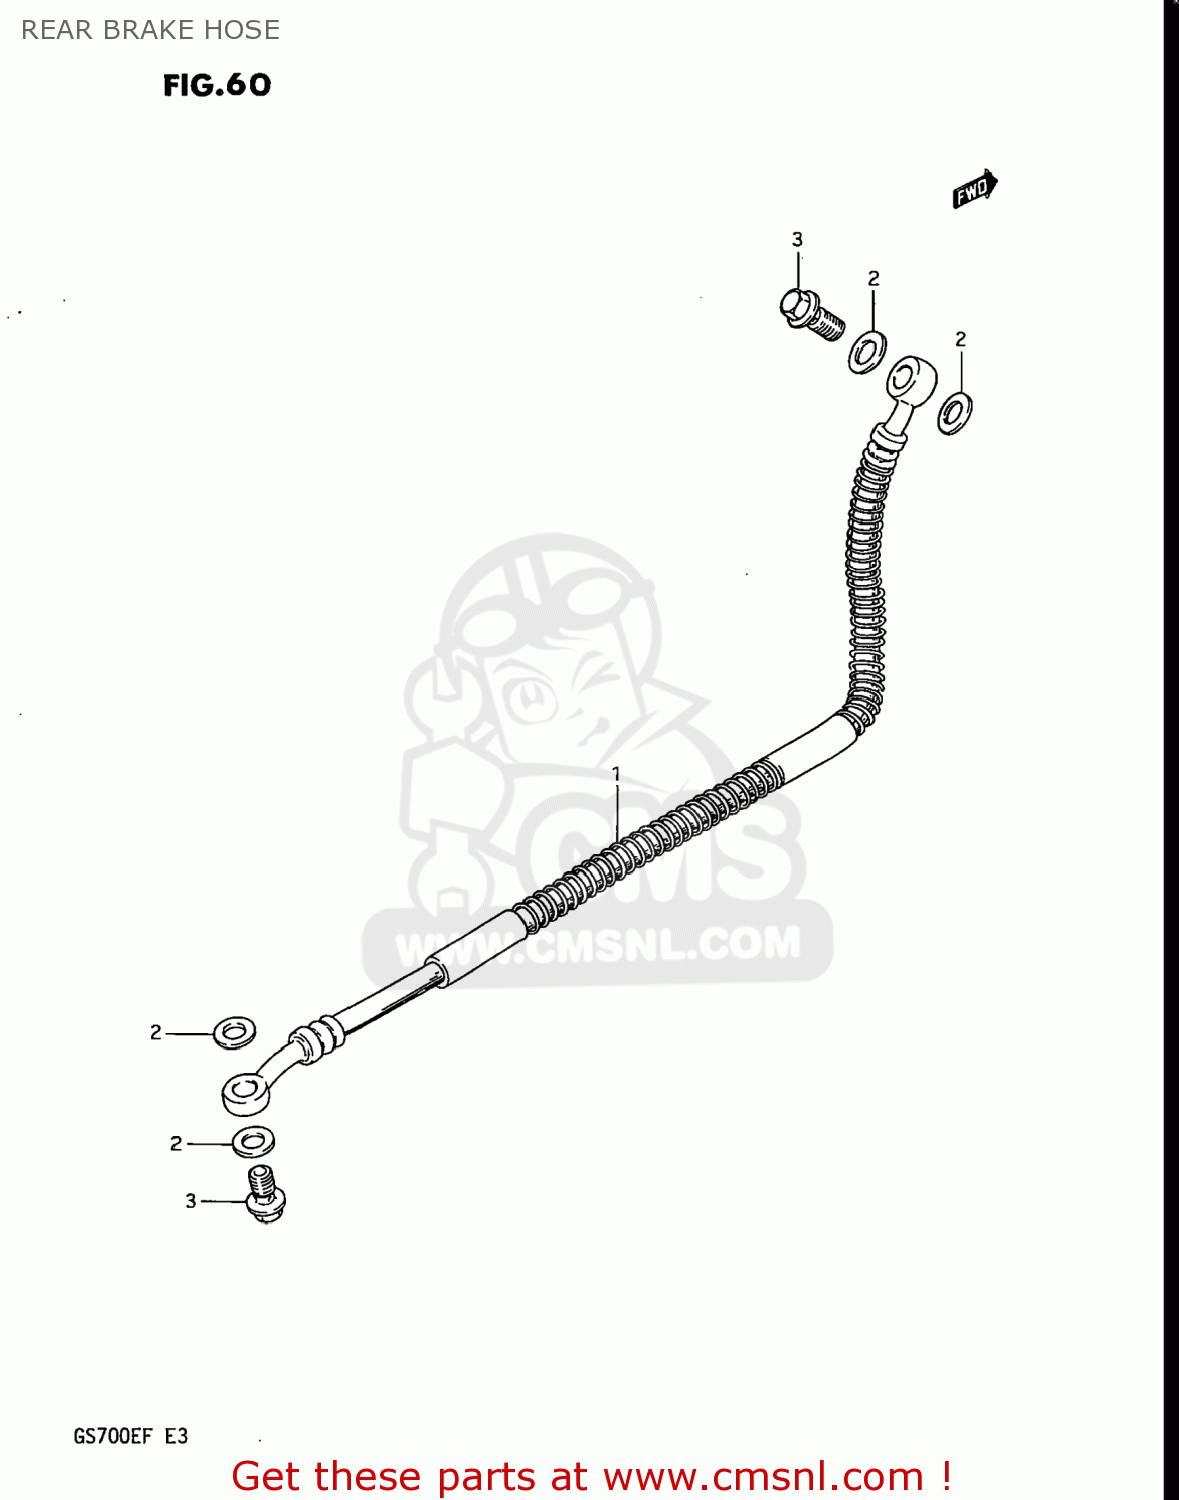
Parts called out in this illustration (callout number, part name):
1	HOSE,REAR BRAKE
2	WASHER(10X15X1.5)
3	BOLT UNION
